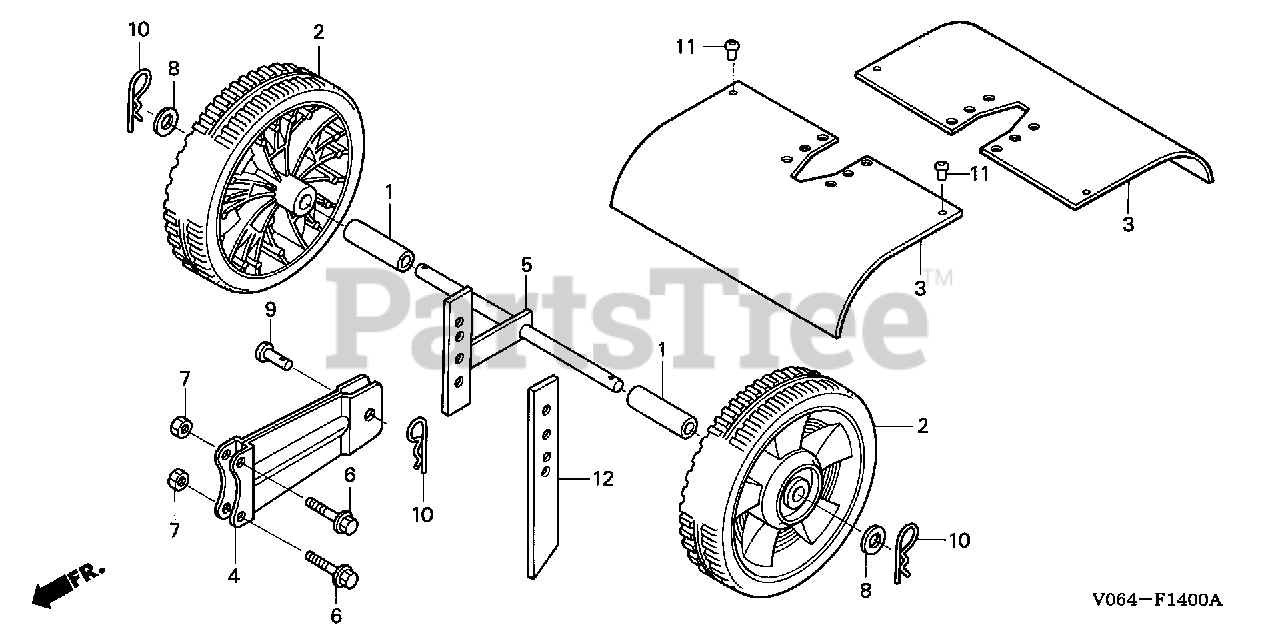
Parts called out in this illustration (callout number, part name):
1	SPACER, WHEEL
2	WHEEL
2	WHEEL, RR.
3	FENDER, FR.
4	HOLDER, DRAG BAR
5	BRACKET
6	SCREW (1/4-20X1)
7	NUT (1/4-20)
8	WASHER (NOT AVAILABLE)
9	PIN (5/16X7/8)
10	PIN, LOCK
11	RIVET (5/32X1/8)
12	BAR, DRAG
